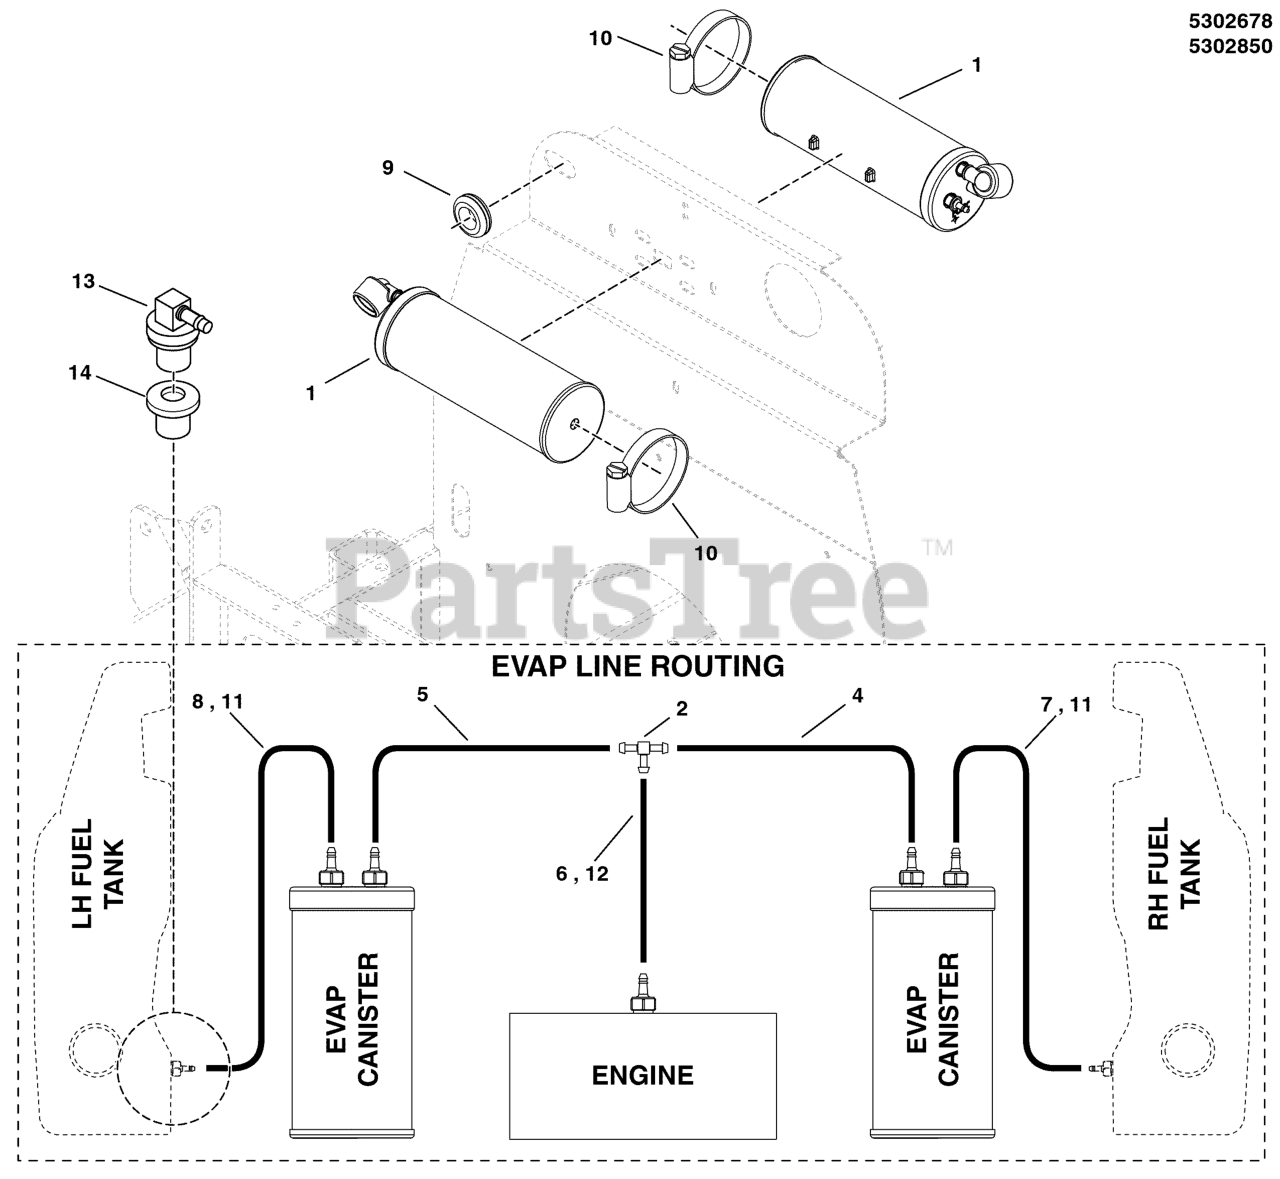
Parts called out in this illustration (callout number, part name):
1	CNSTR, CARB, 9 GAL
2	FITTING, 3/16" TEE, BARB TYPE, HDPE
3	DECAL, EPA CERT - 49 STATE
4	HOSE, VAPOR, 5MM ID, 15.00 LG
5	HOSE, VAPOR, 5MM ID, 1.50 LG
6	HOSE, VAPOR, 5MM ID, 18.50 LG
7	HOSE, VAPOR, 5MM ID, 42.50 LG
8	HOSE, VAPOR, 5MM ID, 39.00 LG
9	GROMMET, 7/8
10	CLAMP-HOSE WORM DR
11	HOSE, VAPOR, 5MM ID, 42.00 LG
12	HOSE, VAPOR, 5MM ID, 16.00 LG
13	REMOTE VENT ASSEMBLY
14	GROMMET (SV)
